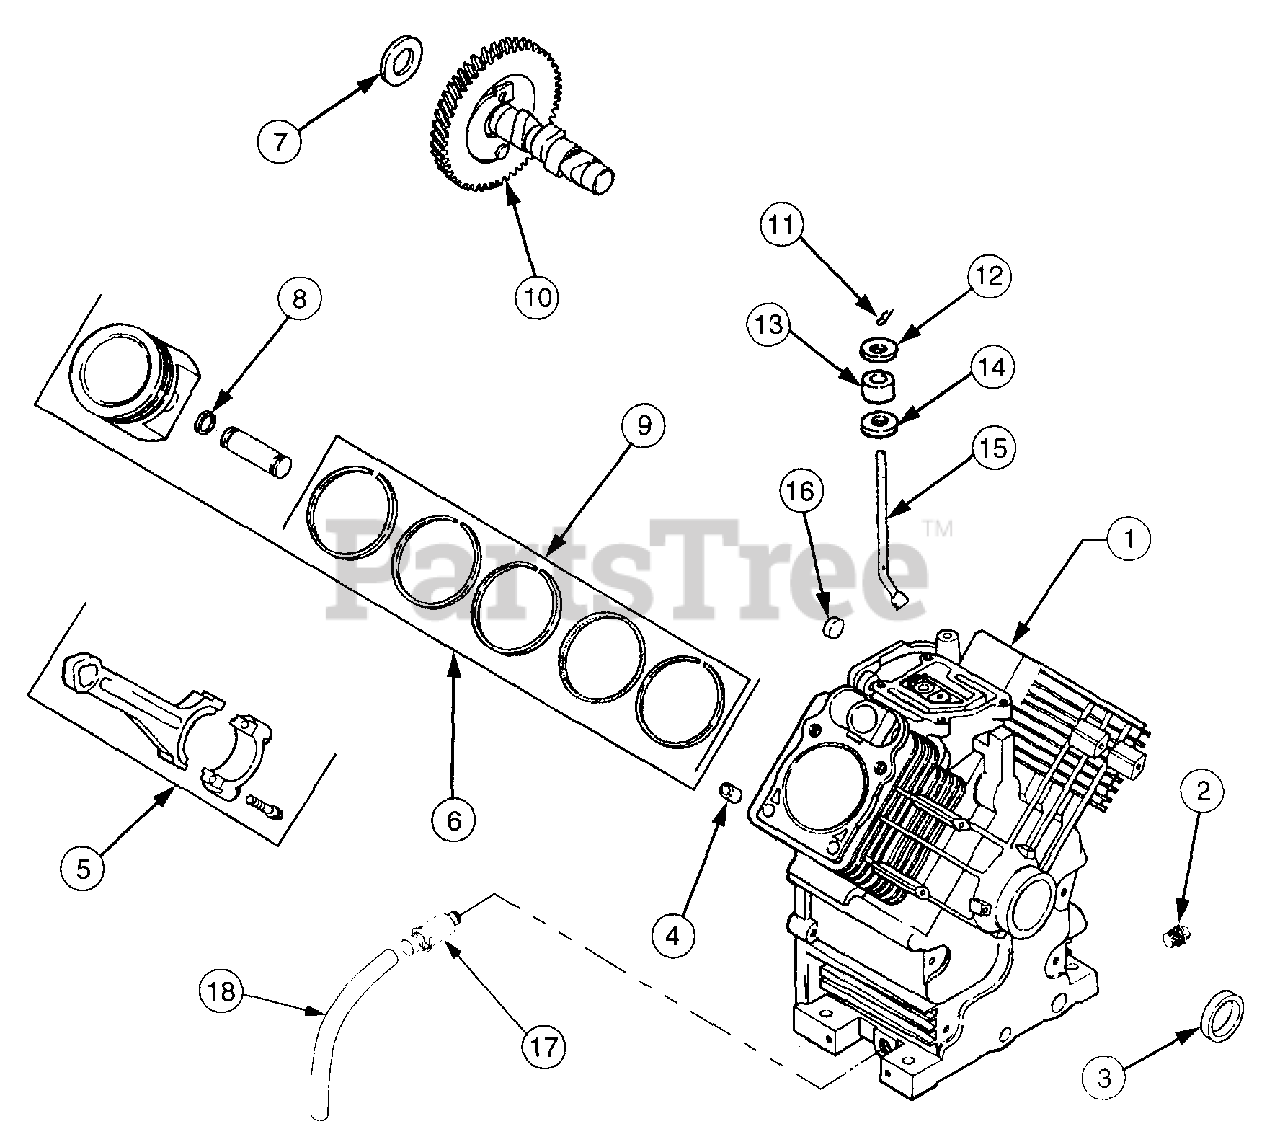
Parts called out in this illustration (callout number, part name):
1	Cylinder Block
2	Plug, Hex Hd, 3/8
3	Seal, Front Oil
4	Pin, Locating Dowel
5	Rod, Connecting, Std
6	Piston w/Ring Set, Std
7	Shim, Camshaft, .0320
8	Retainer, Piston Pin
9	Ring Set, Std
10	Camshaft Assembly
12	Washer, Plain
13	Seal, Governor Cross Shaft
14	Washer, Plain
15	Shaft, Governor Cross
16	Plug, Cup
17	Drain, Oil
18	Hose, Oil Drain
